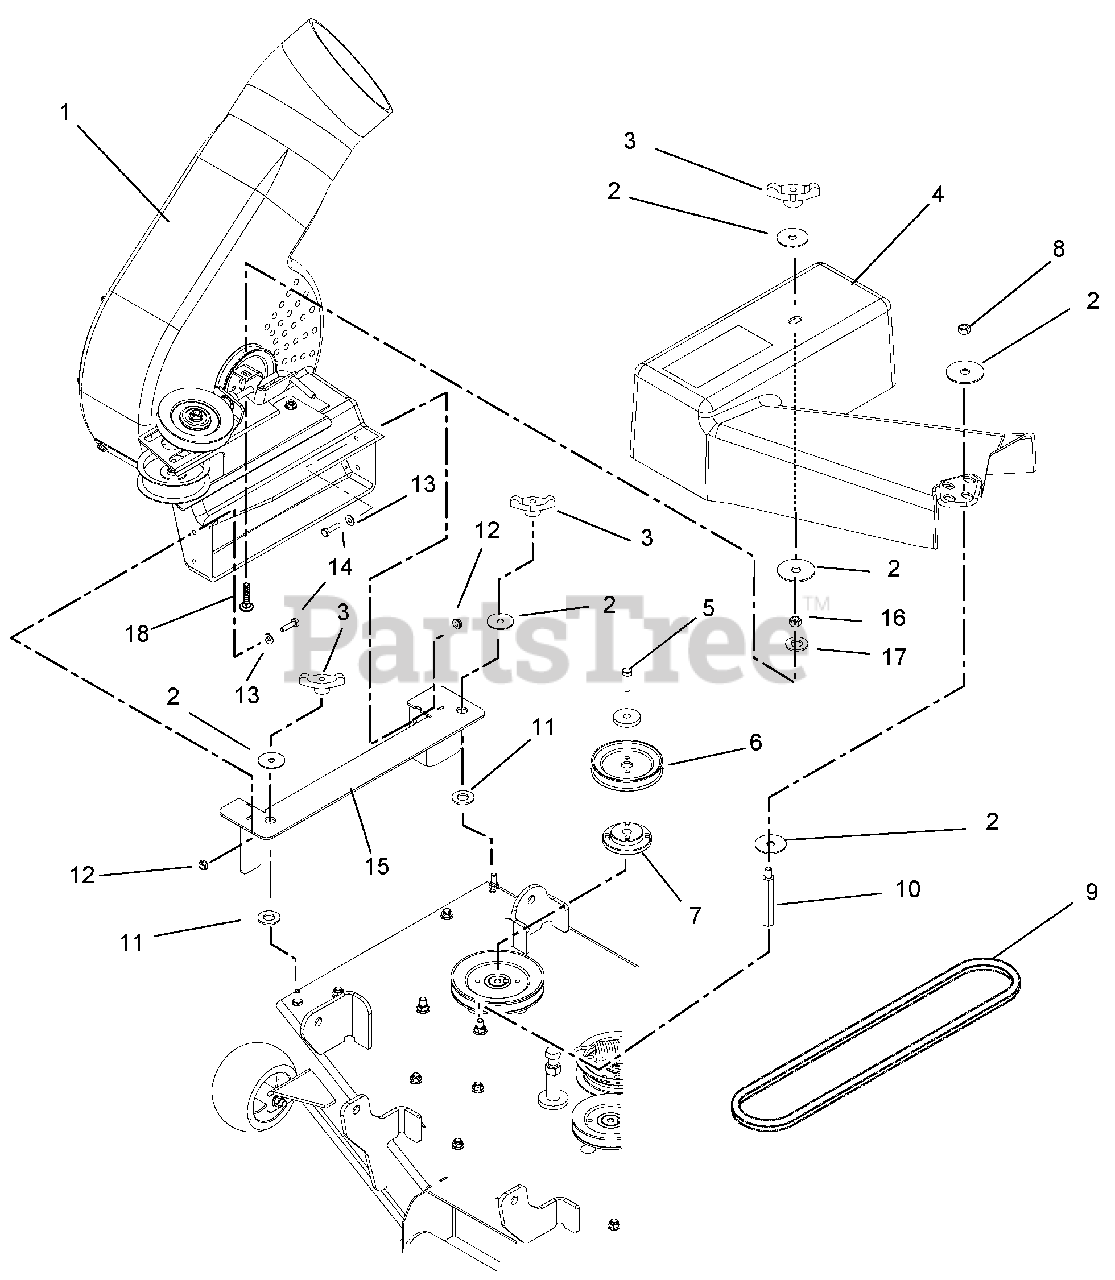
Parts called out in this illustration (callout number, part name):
1	Housing, Blower
2	Washer, Flat, Steel.38 x 1.50 x .062
3	Knob, Wing .312-18
4	Belt Cover, 42-Inch Decks
5	Bolt, Hex .38-16 x 1.75 – Grade 8
6	Sheave, 4.00 Diameter
7	Assembly, Sheave Adapter
8	Nut, Locking, Center .31-18
9	V-Belt, HA Wrapped
10	Standoff, 2.75 x 5/16-18
11	Washer, Flat, Steel .656 x 1.25 x .10
12	Nut, Locking-Top-Flange .25-20
13	Washer, Flat, Steel .281 x .62 x .065
14	Bolt, Hex .25-20 x 1.00 Grade 5
15	Bracket, Blower Weldment
16	Nut, Jam .312-18
17	Washer, Flat Steel, .312 x .734 x .065
18	Bolt, Round Head Square Neck, .31-18 x 1.50
